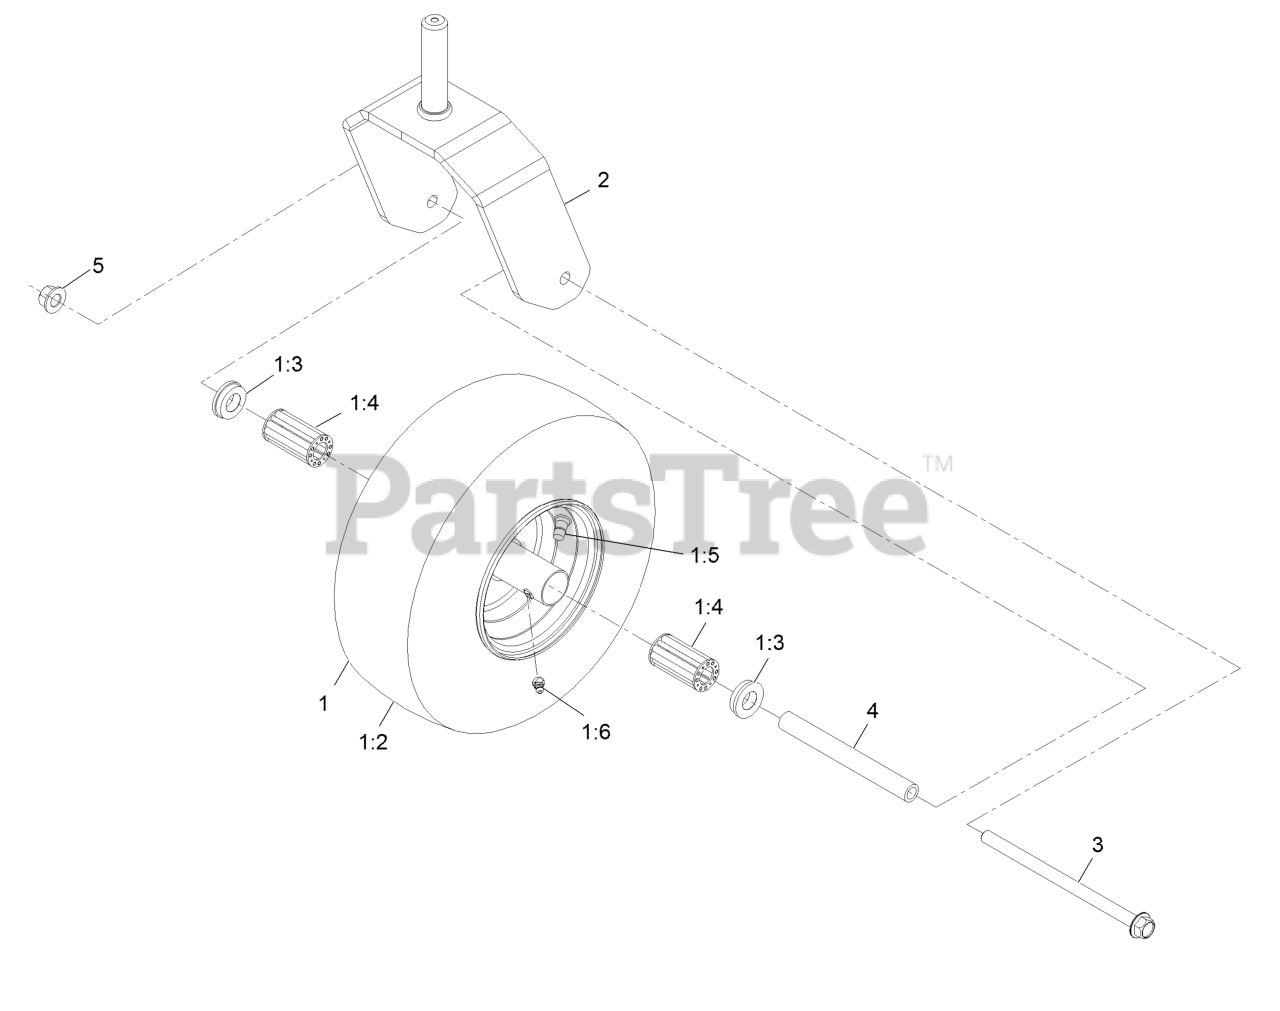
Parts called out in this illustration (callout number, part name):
1	ASM-Wheel And Tire 13X6.50-6
1:3	Bushing-Flange
1:4	Bearing-Roller, Wheel
1:5	Valve
1:6	Fitting-Zerk
2	Fork-Caster
3	Screw-HHF
4	Spanner-Wheel, Caster
5	Nut-Lock 1/2-13
